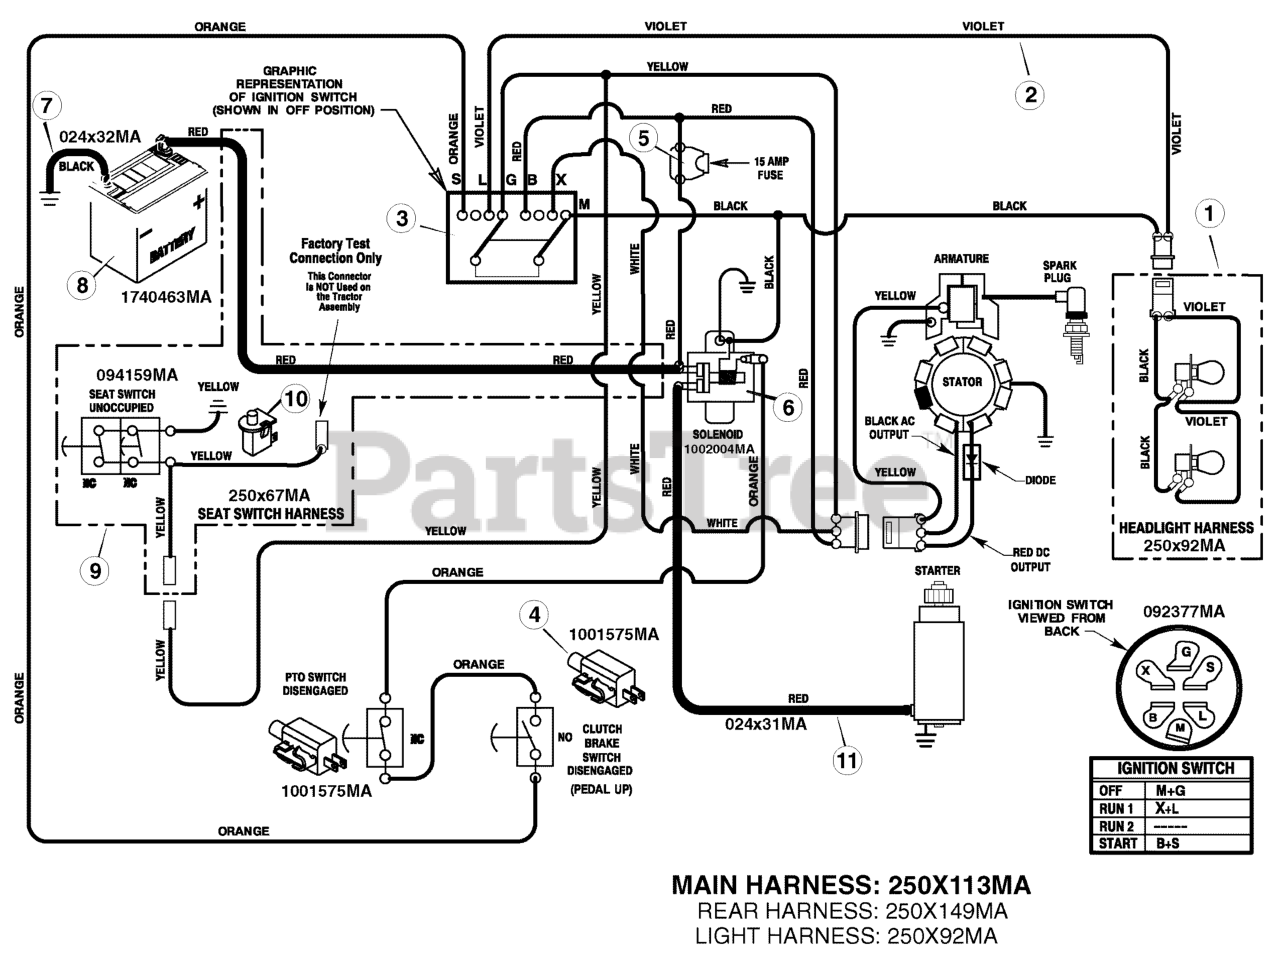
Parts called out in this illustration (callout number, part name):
1	Harness, Light Wire
2	Harness, Chassis Wire
3	Switch, Ignition
4	Switch, Limit
6	Solenoid
7	Cable, Battery Ground
9	Harness, Seat Switch Wire
10	Switch, Seat Sensor
